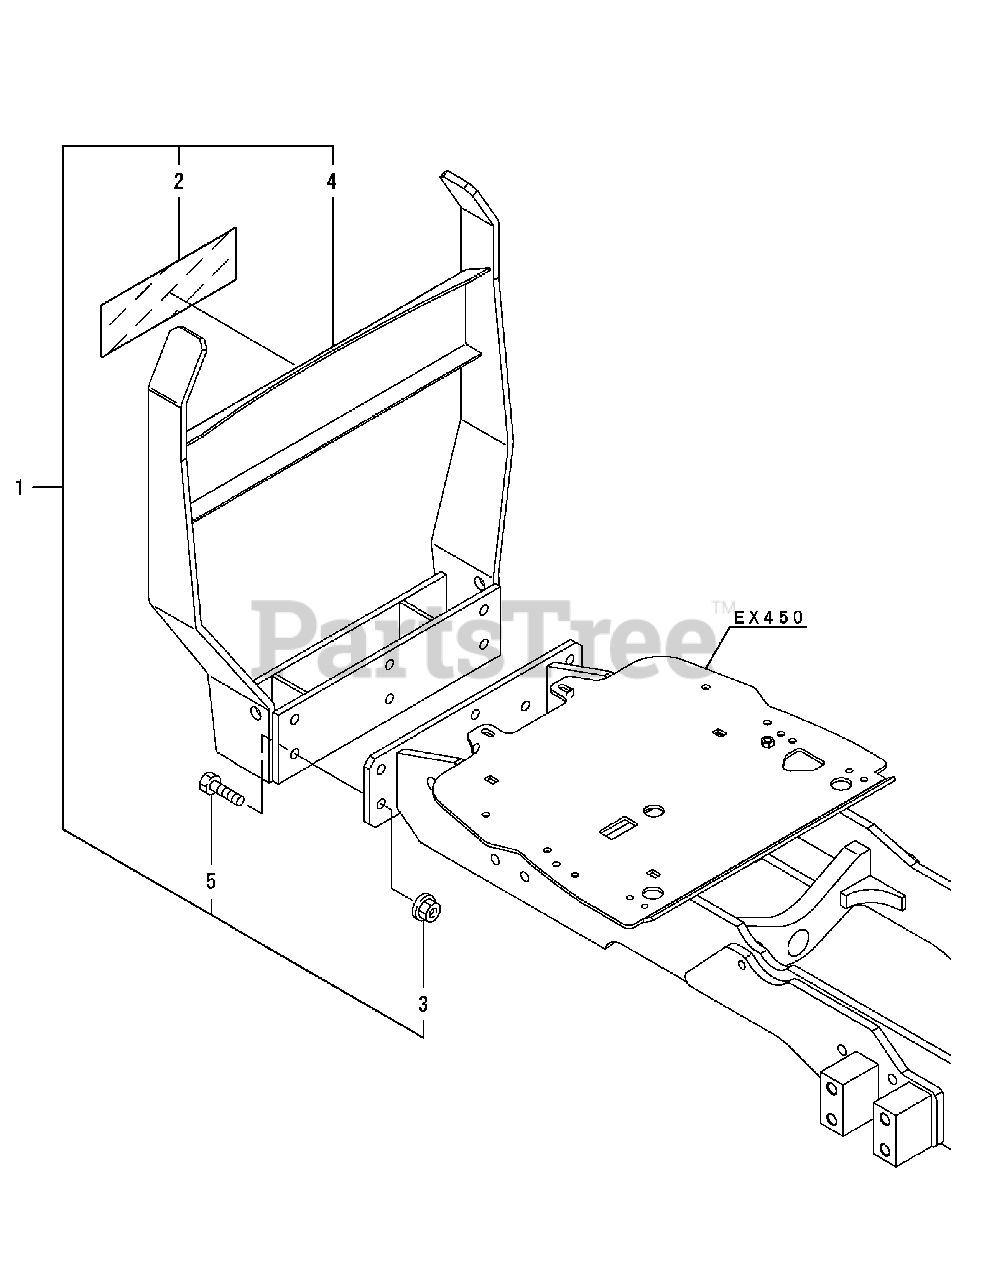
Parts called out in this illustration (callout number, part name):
1	GRILLE GUARD KIT
2	LABEL, GRILL GAURD
4	GRILLE GUARD CMP
